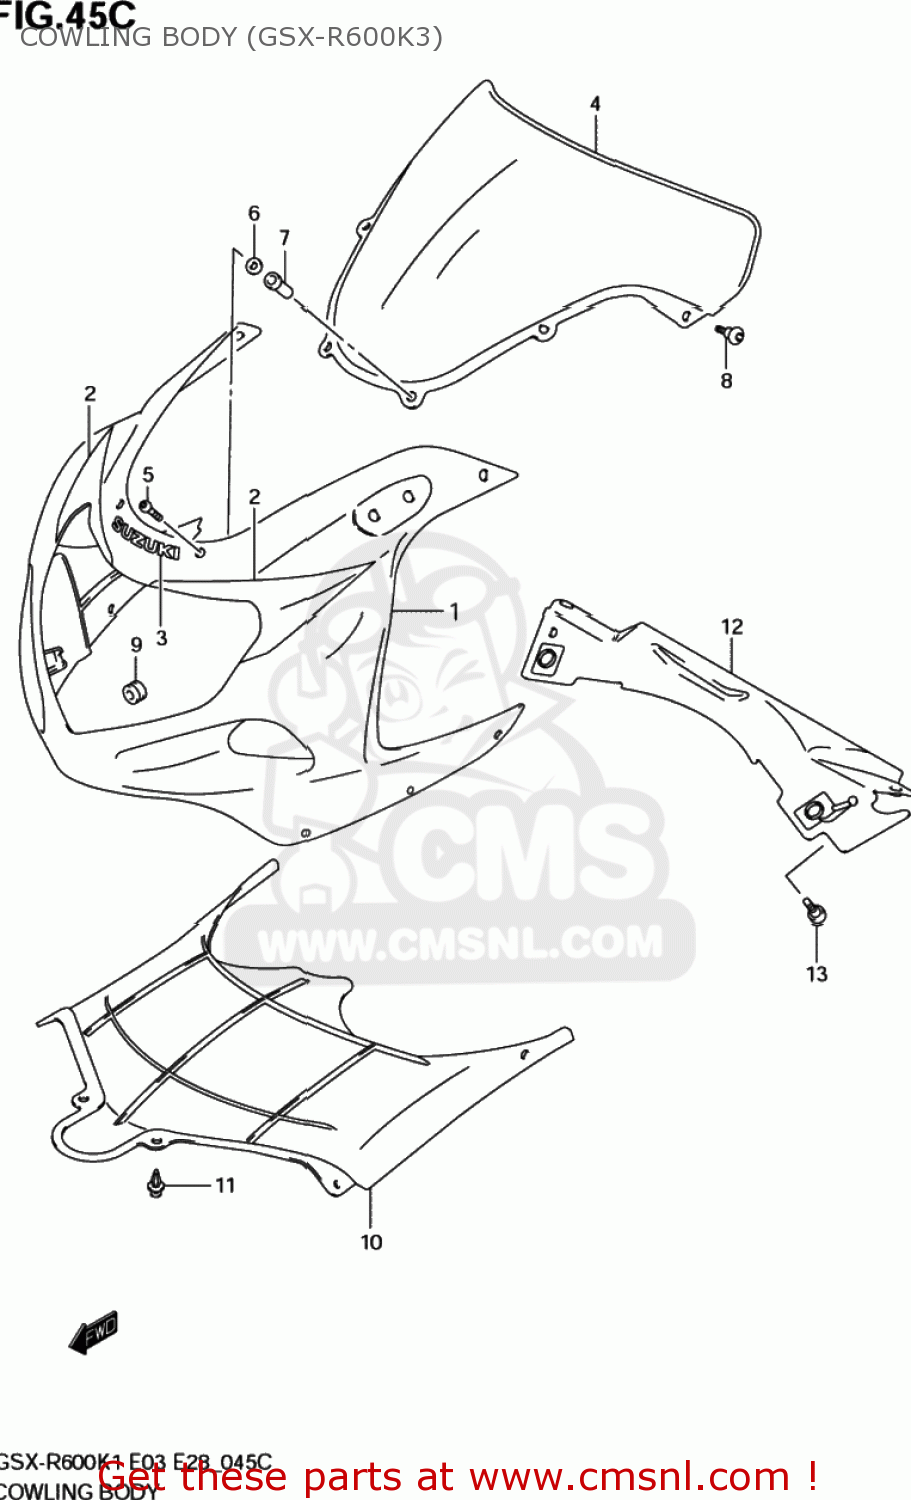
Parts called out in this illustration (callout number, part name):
1	COWLING,BODY(BLACK)
2	TAPE SET,COWL BODY
3	EMBLEM,SUZUKI
4	WINDSCREEN
5	SCREW(5X14)
6	WASHER
7	NUT
8	SCREW(5X16)
9	CUSHION
10	COVER,BODY COWLING
11	CLIP(BLACK)
12	COVER,COWLING FR LWR
13	BOLT(5X16)
